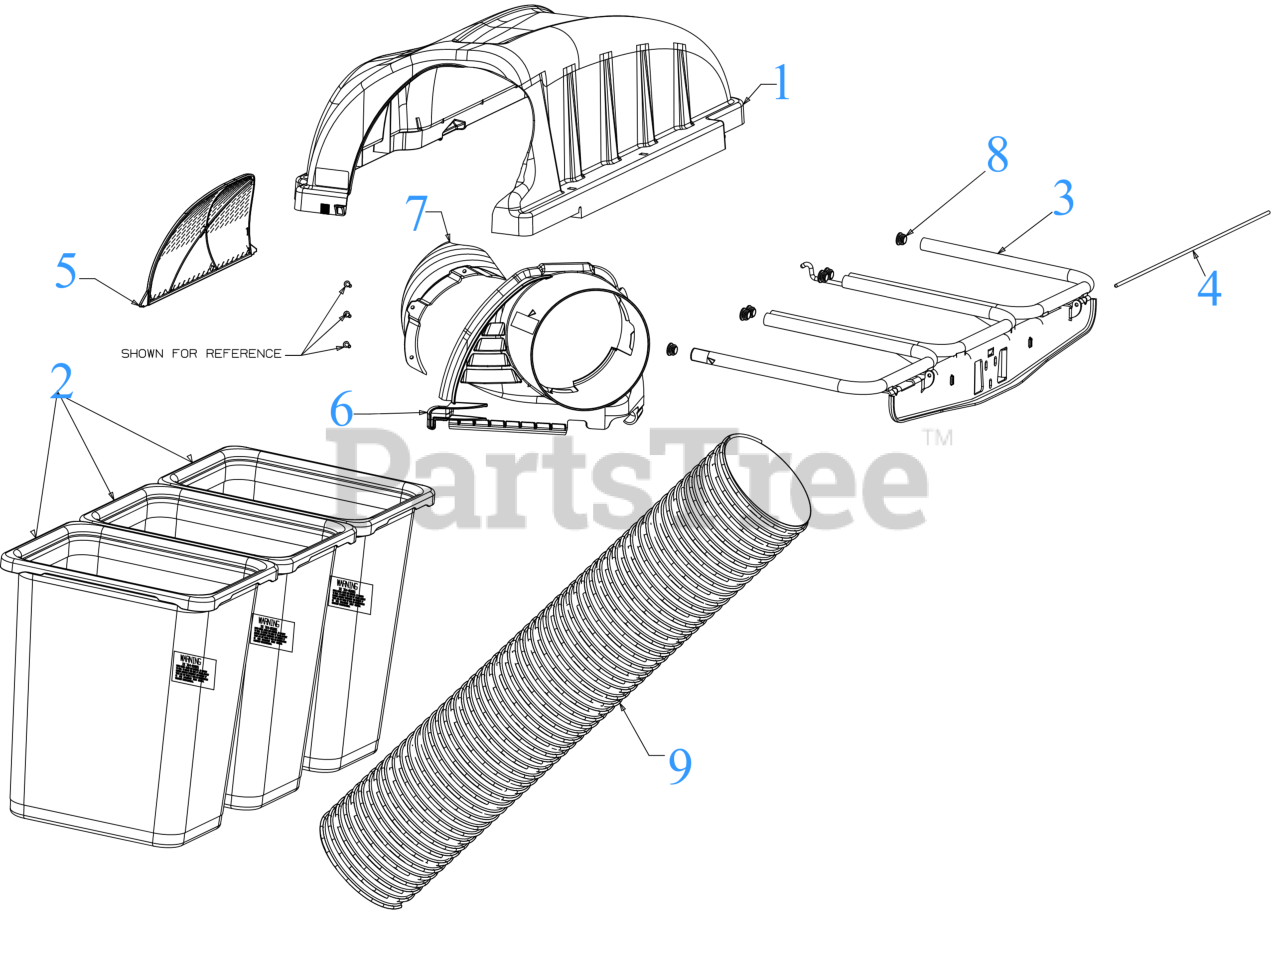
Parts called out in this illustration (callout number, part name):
1	TRIPLE BAGGER COVER
2	GRASSBAG ASSEMBLY W/HARD BOTTOM (LG)
3	SUPPORT ASSEMBLY
4	HINGE PIN
5	BAGGER COVER SCREEN
6	UPPER CHUTE SUPPORT
7	BAGGER DEFLECTOR
8	END PLUG
9	9" BAGGER HOSE
